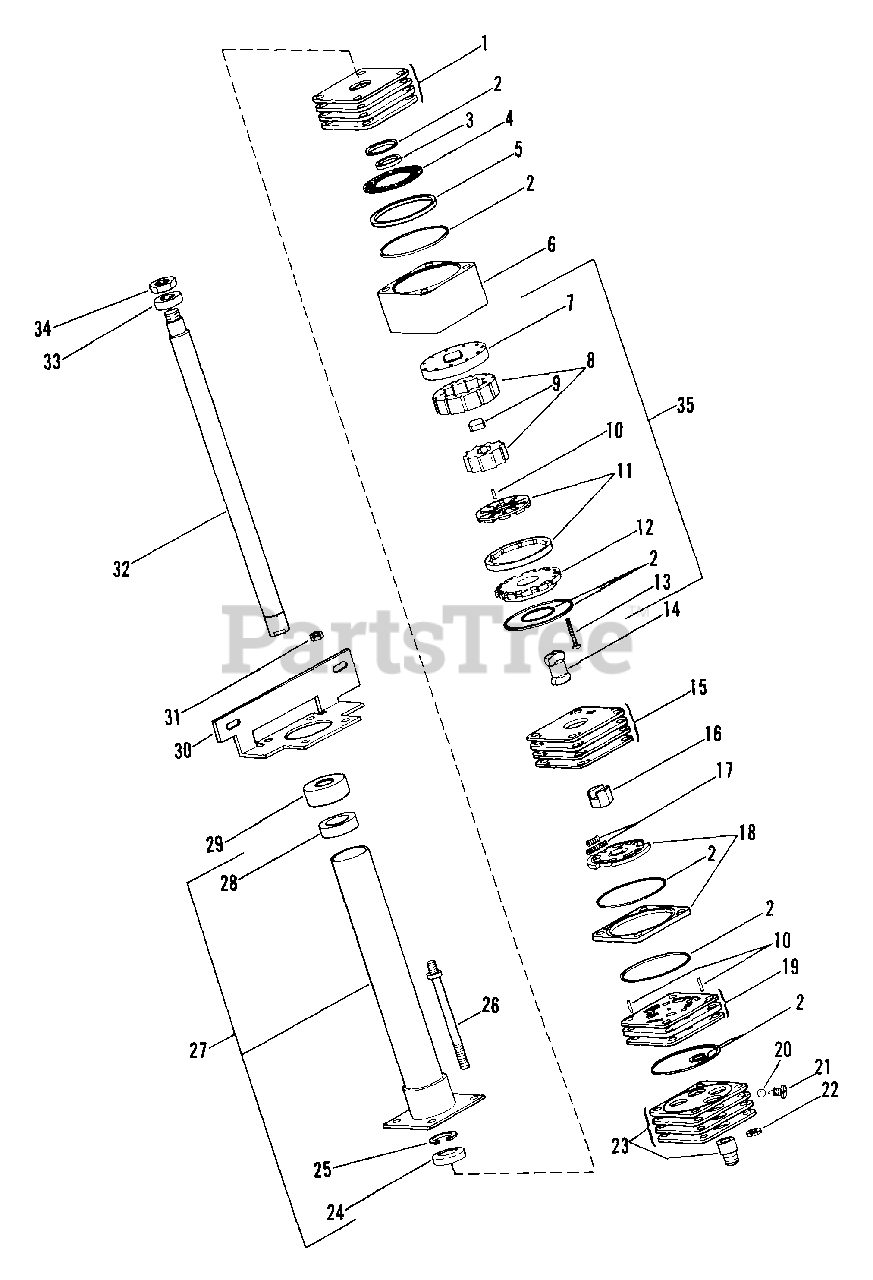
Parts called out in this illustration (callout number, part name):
1	UPPER COVER PLATE
2	SEAL SERVICE ASS'Y
3	SEAL SPACER
4	THRUST BEARING
5	SPACER-ROSS SERVICE
6	METERING RING
7	DRIVE PLATE
9	SPACER-ROSS SERVICE
10	NEEDLE ROLLER SERVICE ASS'Y
11	COMMUTATOR & RING ASS'Y
12	COMMUTATOR COVER
13	SCR-SPECIAL ROSS
14	DRIVE LINK
15	ISOLATION MANIFOLD
16	HEX DRIVE
17	SPRING SERVICE ASS'Y
18	VALVE & RING ASS'Y
19	PORT MANIFOLD
20	BALL - STEEL
21	PLUG & O-RING ASS'Y
22	NUT-LK-CTR .312-24 PL
23	PORT COVER
25	RG-RTNG ROSS #401465
26	STUD-SPECIAL SV ROSS
27	UPPER COVER & JACKET TUBE ASS'
28	COLUMN BEARING SET
30	BRACKET
31	NUT-LK TOP .312-24 PL GR C
32	INPUT SHAFT SERVICE ASS'Y
33	DUST COVER
34	NUT-LK-JAM .625-18 YWZC
35	METERING ASS'Y
